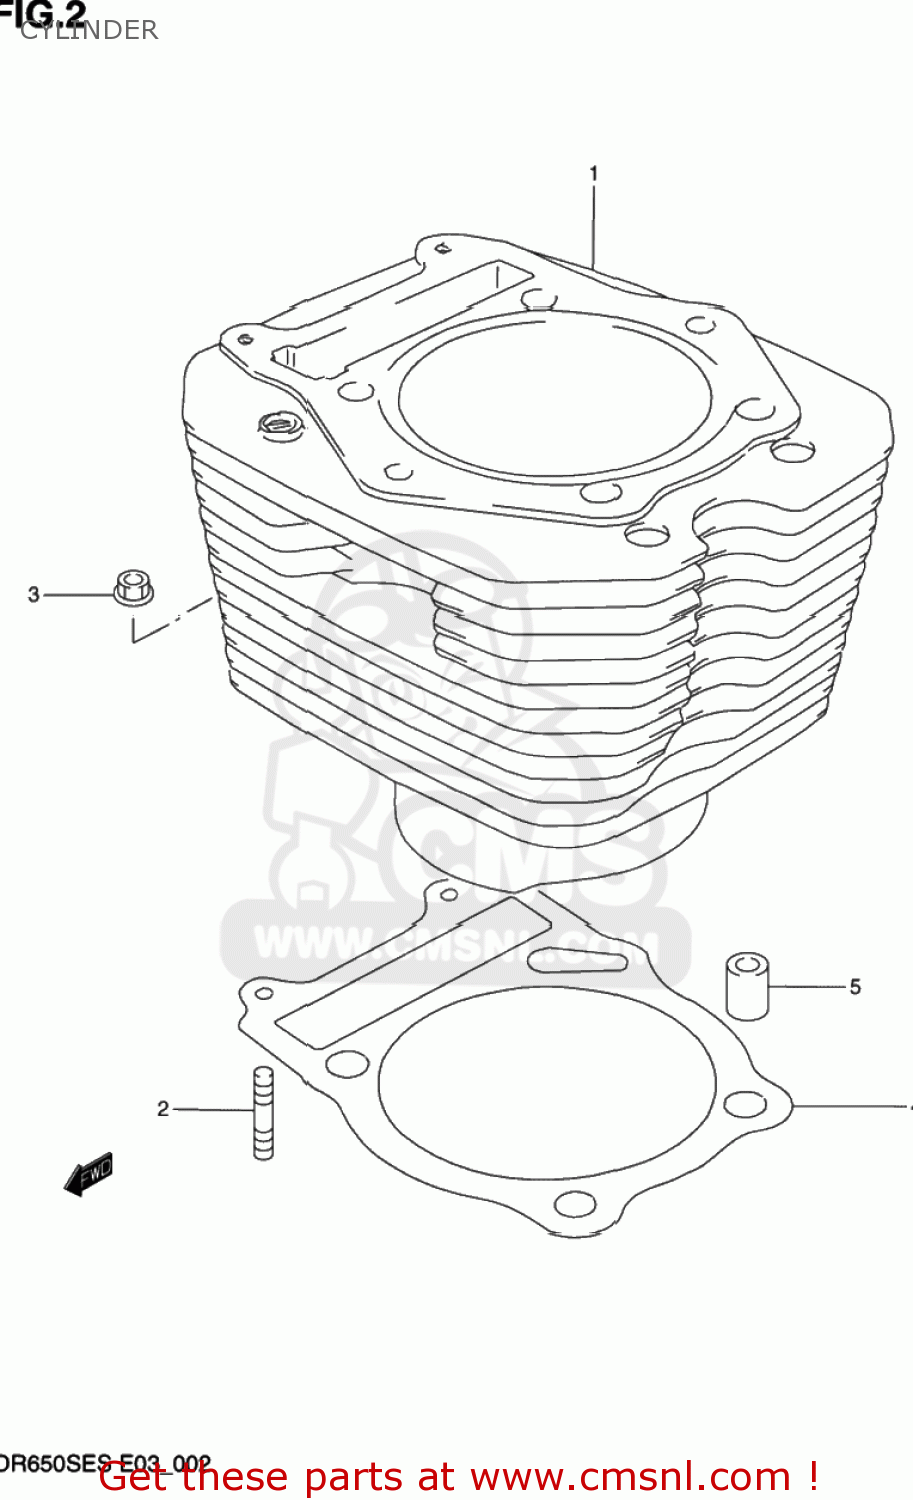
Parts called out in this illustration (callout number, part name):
1	CYLINDER
2	STUD 6X20
3	NUT
4	GASKET,CYLINDER (NAS)
5	PIN
